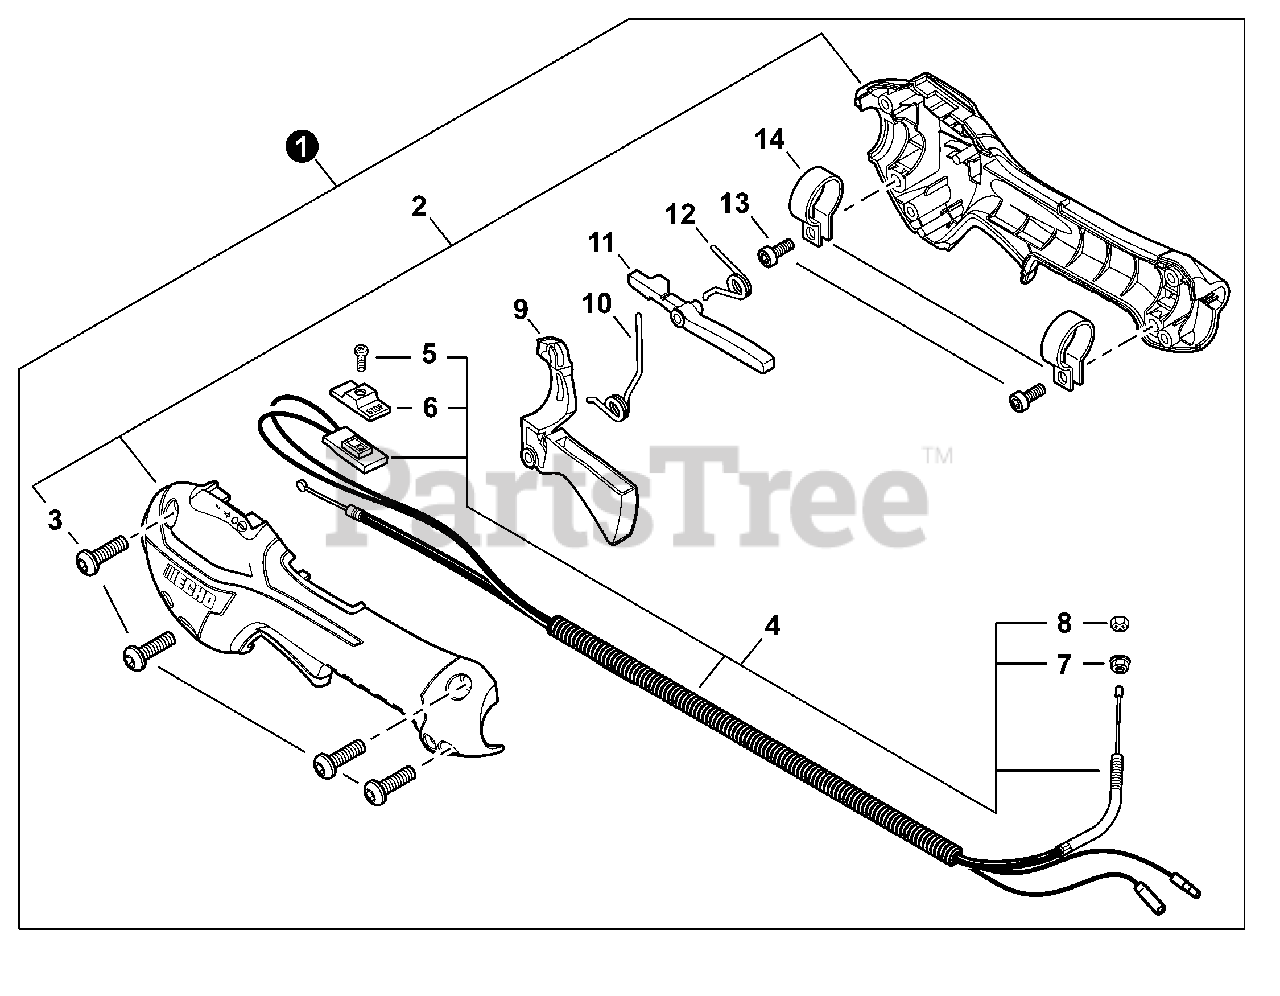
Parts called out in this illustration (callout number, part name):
1	CONTROL HANDLE ASSY
2	CONTROL HANDLE KIT
3	BOLT, TORX 5×16
4	CABLE ASSY, CONTROL
5	SCREW 3×10
6	KNOB, SWITCH - ORANGE
7	NUT, FLANGE 6
9	TRIGGER, THROTTLE
10	SPRING, TORSION
11	LEVER, THROTTLE LOCKOUT
12	SPRING, TORSION
13	BOLT, TORX 5×16
